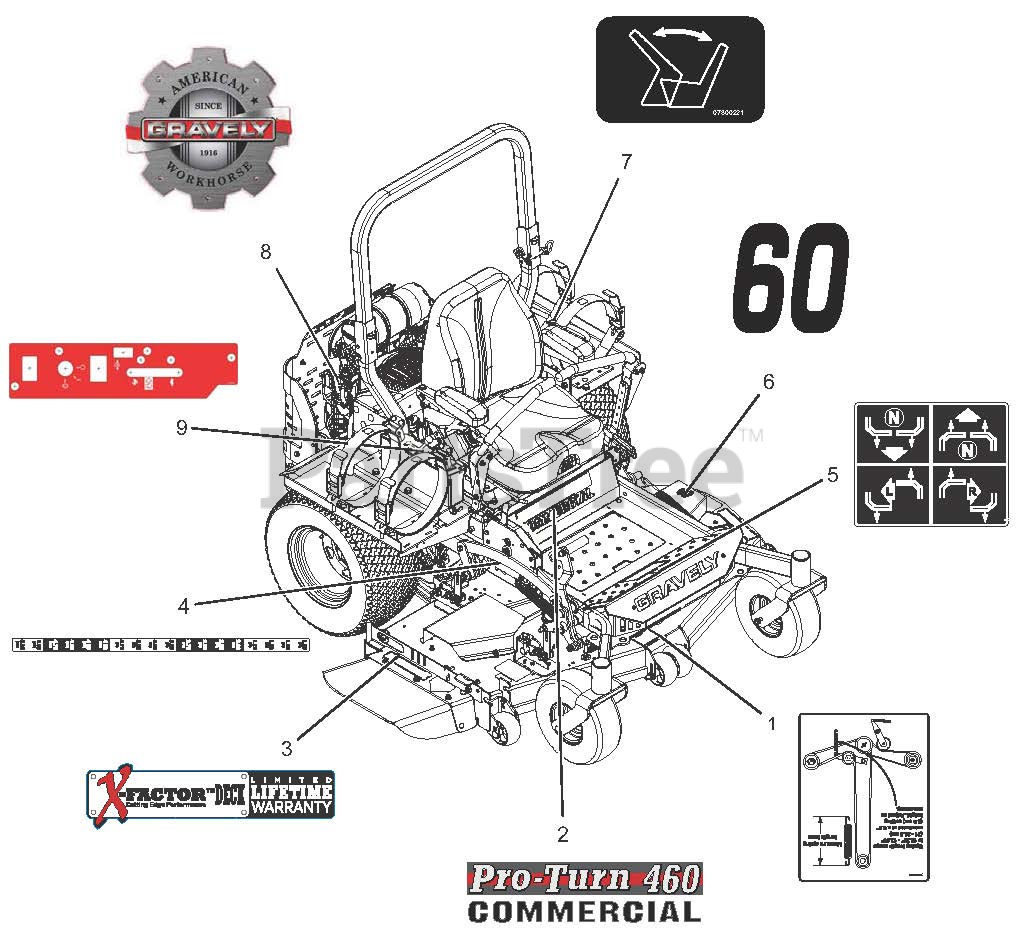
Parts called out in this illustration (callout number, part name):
1	DECAL, BELT DIAGRAM
2	DECAL, PT460
3	DECAL-X-FACTOR DECK
4	DECAL, PT400 HEIGHT OF CUT
5	DECAL, INSTRUCTIONAL-STEERING
6	DECAL, 60"
7	DECAL - SEAT RELEASE
8	DECAL, GRAVELY HERITAGE-LARGE
9	DECAL, CONTROL PANEL-LP
